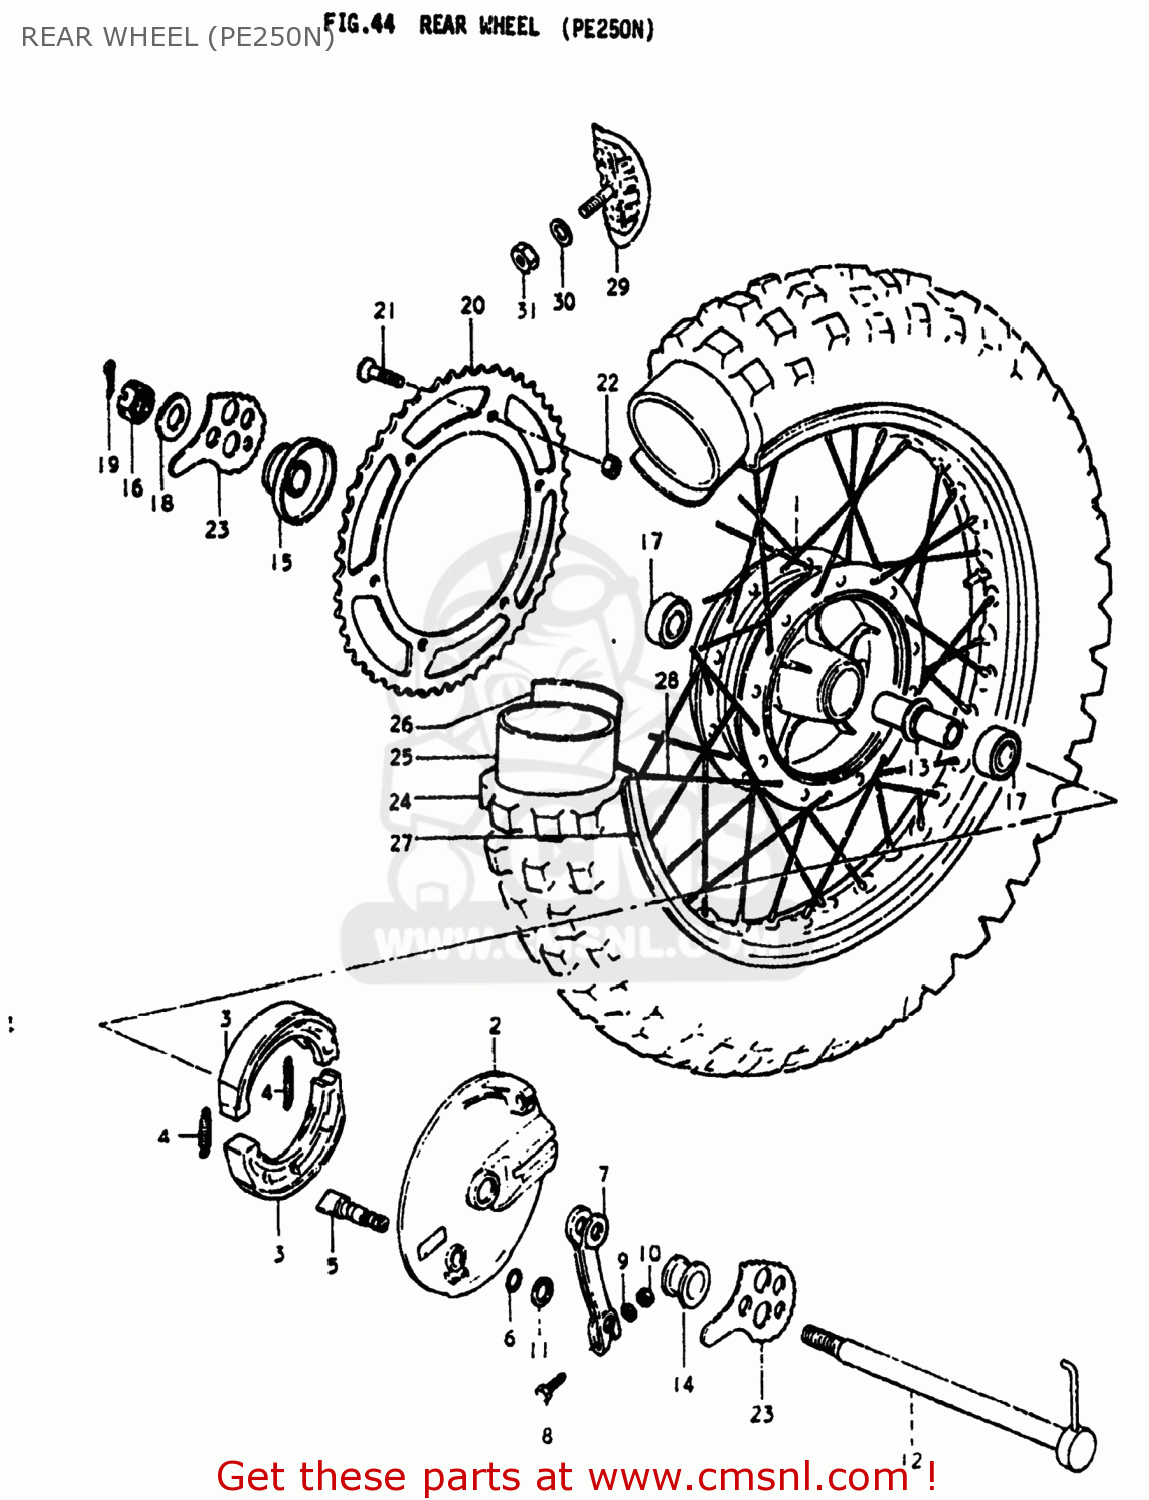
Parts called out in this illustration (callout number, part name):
1	HUB REAR
2	PANEL,REAR HUB
3	SHOE,BRAKE
4	SPRING
5	CAM,FRONT BRAKE
6	O-RING,BOSS
7	LEVER,REAR BRAKE CAM
8	BOLT
9	WASHER
10	NUT
11	WASHER (15X24X1.6)
12	AXLE,REAR
13	SPACER,REAR HUB BEARING
14	SPACER,REAR AXLE,RIGHT
15	SPACER,REAR AXLE
16	NUT
17	BEARING
18	WASHER
19	PIN, COTTER
20	SPROCKET,REAR
21	SCREW
22	NUT
23	ADJUSTER,CHAIN
24	TIRE
25	TUBE ASSEMBLY,WHEEL,INNER
26	PROTECTOR,WHEEL,INNER
27	RIM,REAR WHEEL
28	SPOKE SET,REAR
29	STOPPER,BEAD
30	WASHER
31	NUT
